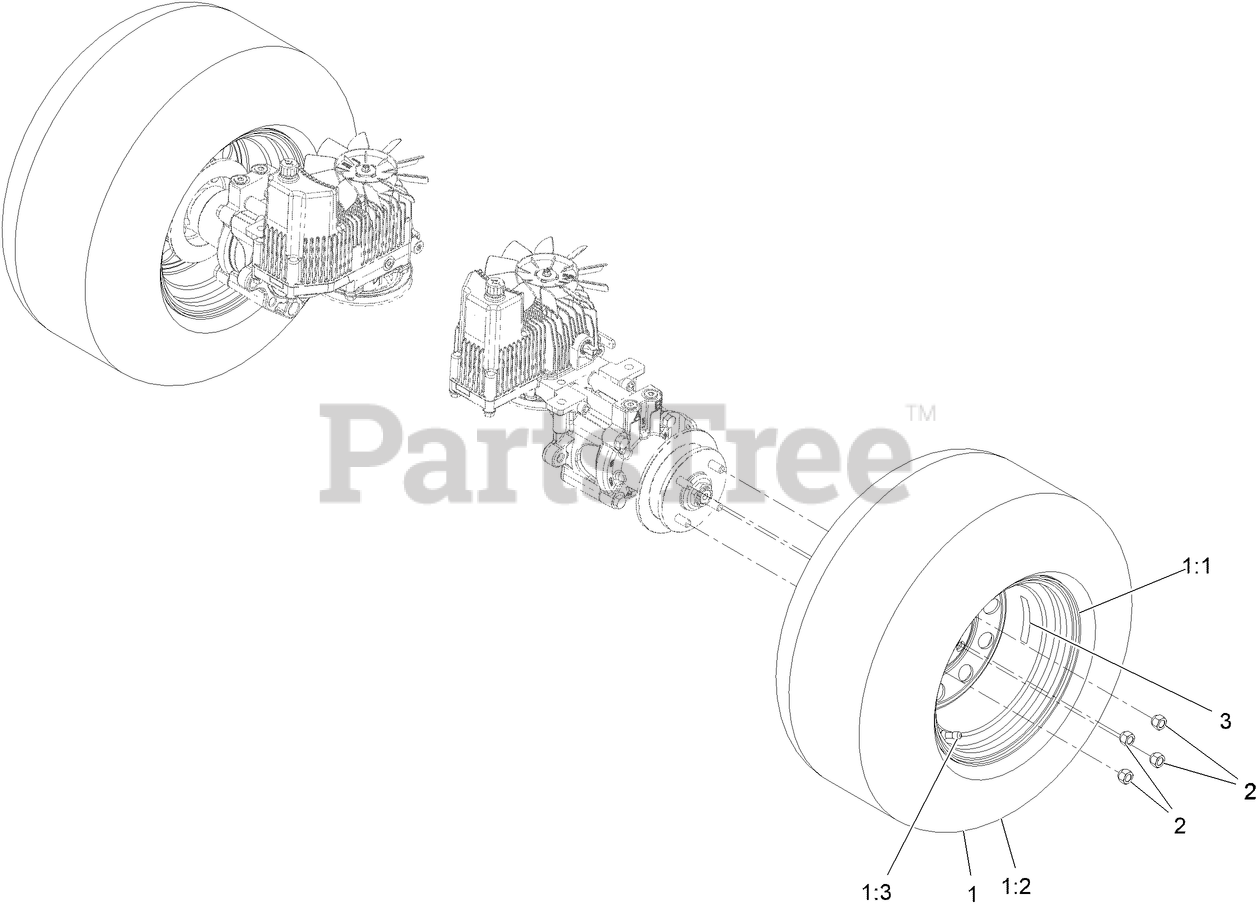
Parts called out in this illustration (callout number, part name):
1	WHEEL AND TIRE ASM
1:3	Stem-Valve
2	NUT-LUG
3	Decal-Wheel Hub
